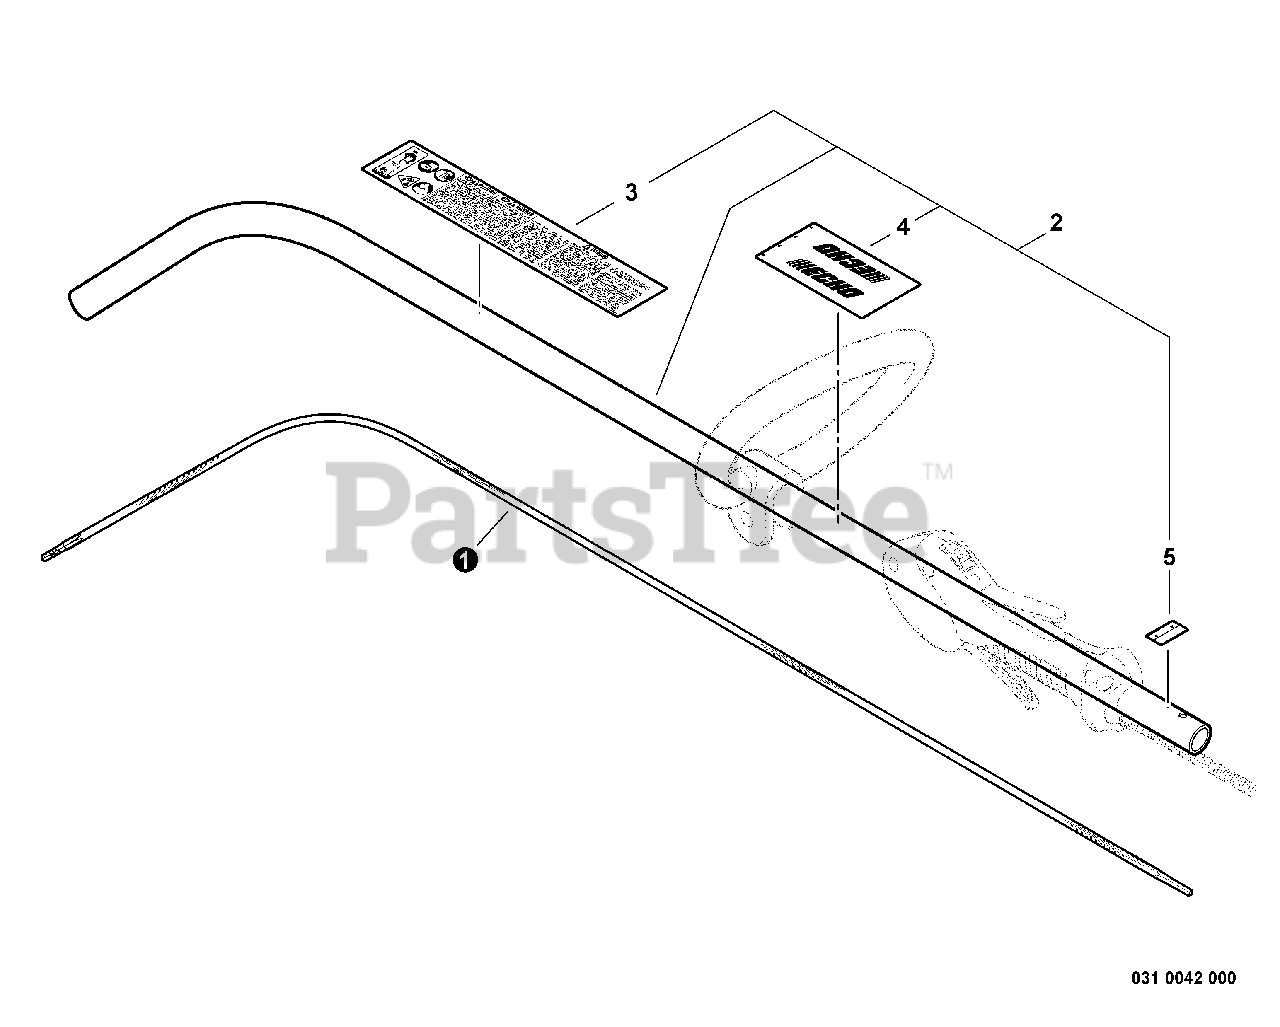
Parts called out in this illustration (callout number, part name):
1	DRIVESHAFT - FLEXIBLE
2	MAIN PIPE ASSY
3	LABEL - CAUTION -- SPANISH
4	LABEL - HANDLE LOCATION
5	LABEL - ALIGNMENT
